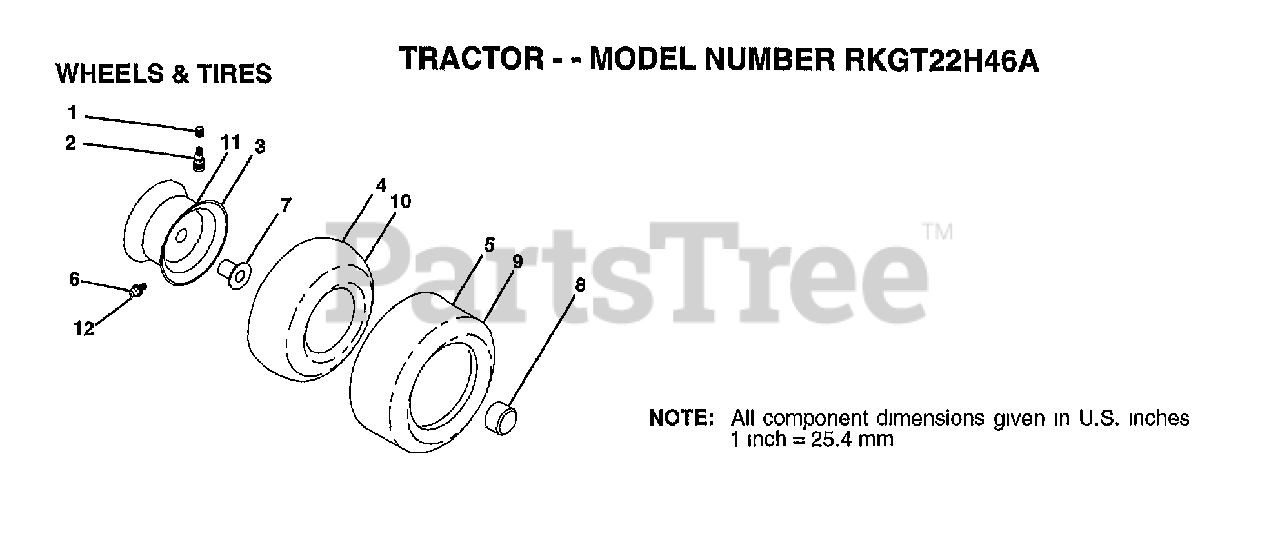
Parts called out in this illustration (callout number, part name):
1	VALVE CAP
2	VALVE STEM LT
3	"RIM ASM 8"" FRT"
4	TUBE.16X6.5/7.5-8
6	FITTING LT
7	"FLANGE, BEARING"
8	HUB CAP
10	TUBE.23X8/10-12
11	"RIM ASM 12"" REAR"
12	ZERK FITTING M
